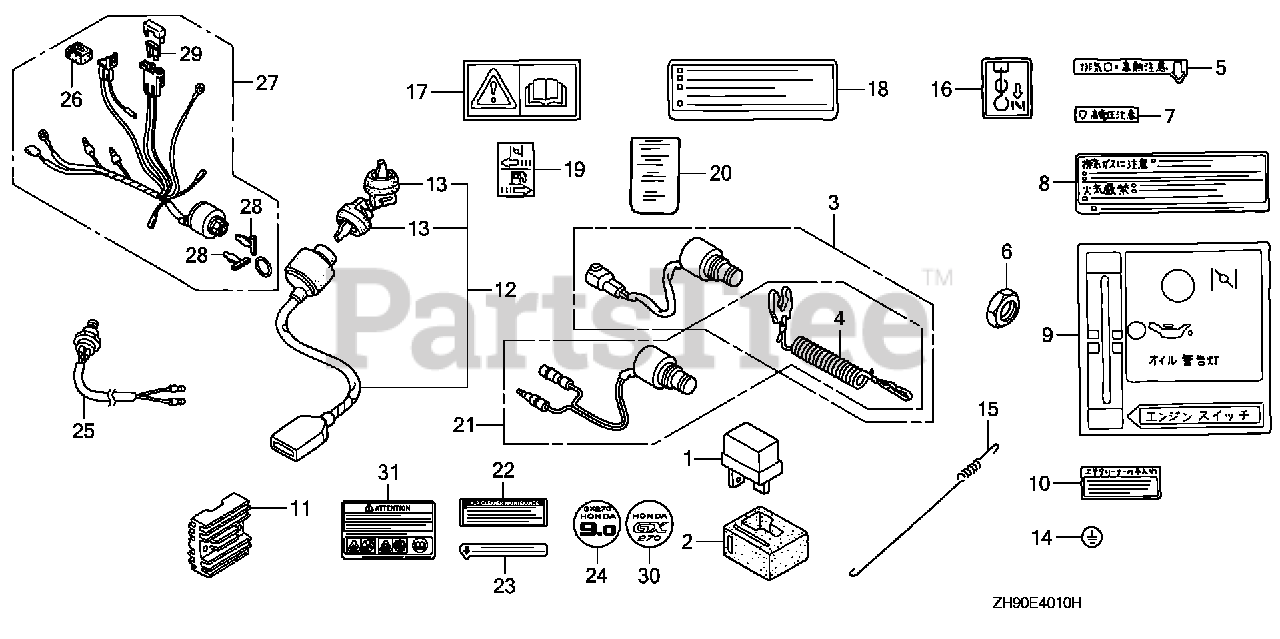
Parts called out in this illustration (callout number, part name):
17	MARK, CAUTION (PICTOGRAPH)
19	MARK, CHOKE (ORANGE)
19	MARK, CHOKE (GRAY)
